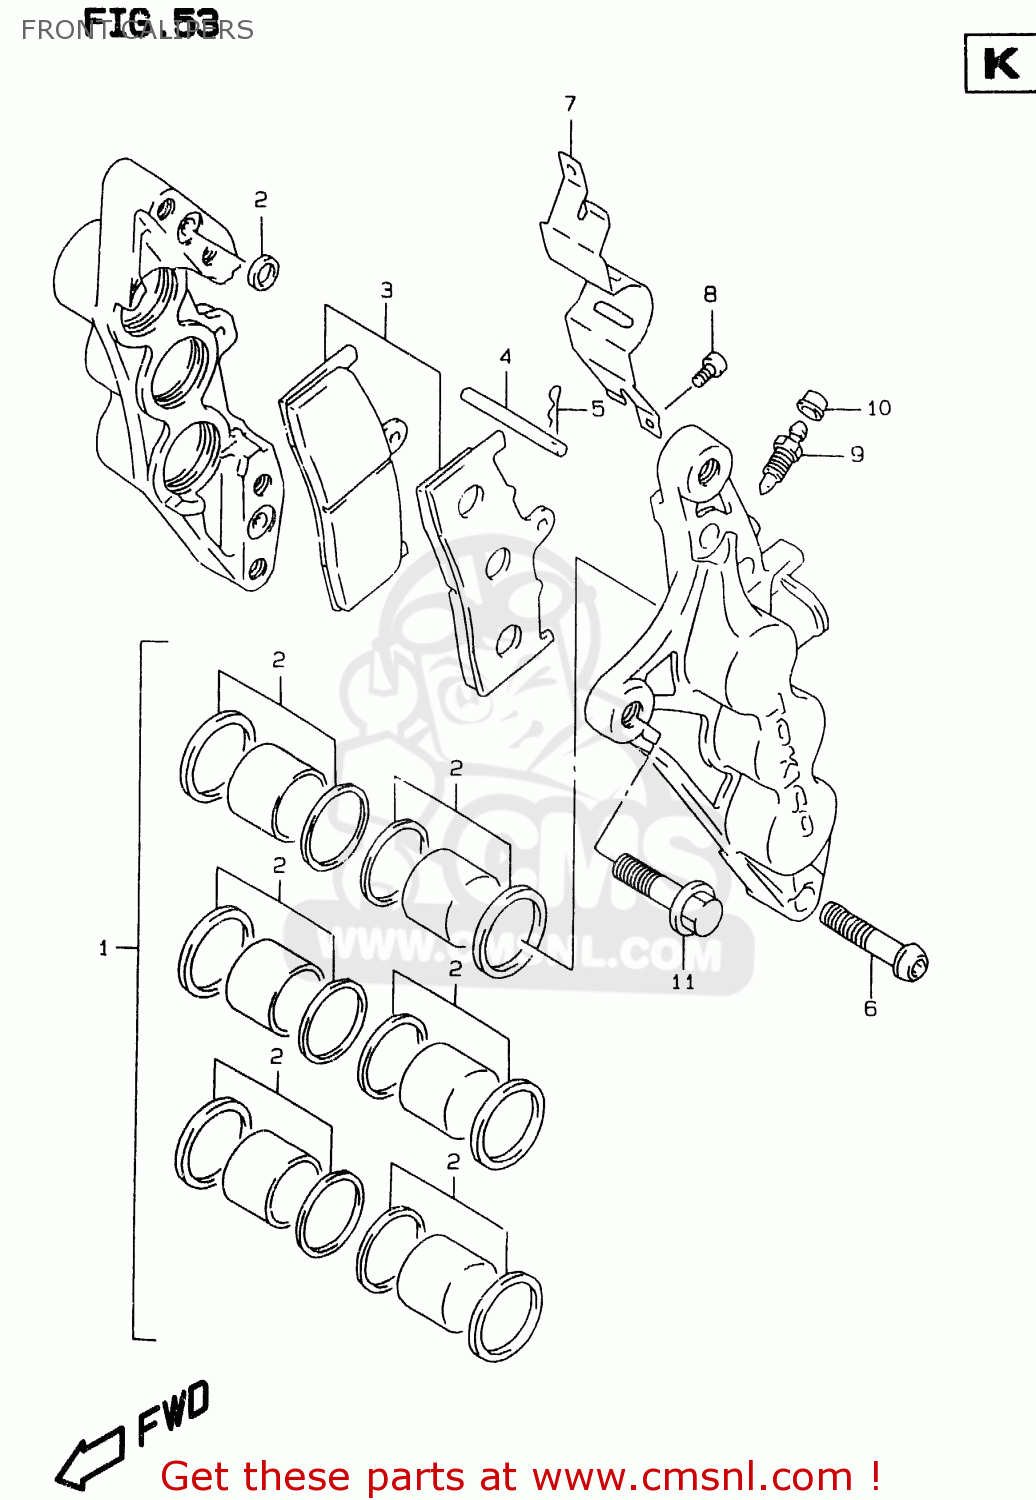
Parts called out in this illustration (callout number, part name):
1	PISTON SET
2	SEAL SET,PISTON
3	PAD SET (NAS)
4	PIN,PAD
5	CLIP,PAD PIN
6	BOLT,HOUSING
7	COVER,CALIPER
8	SCREW
9	BLEEDER
10	CAP,BLEEDER PLUG
11	BOLT(10X30)
